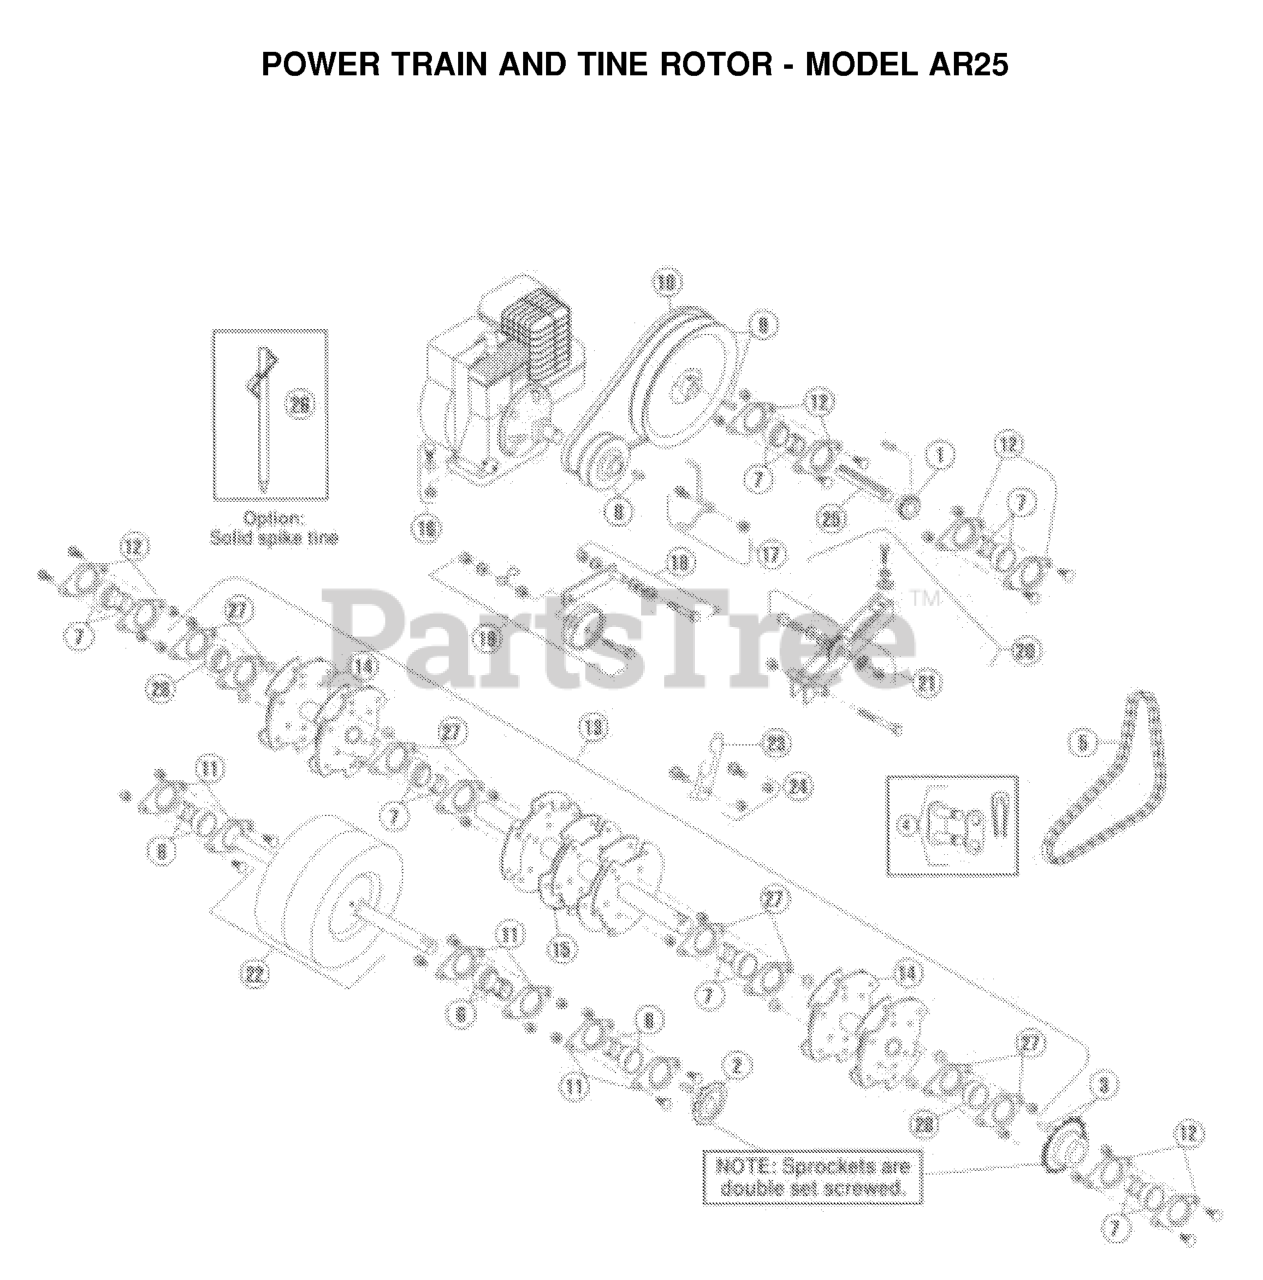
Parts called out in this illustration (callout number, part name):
1	SPROCKET
2	SPROCKET
3	SPROCKET
4	CHAIN LINK #50
5	CHAIN, #50 PERMA LUBE ROLLER
6	BEARING
7	BEARING 1"
8	V-PULLEY, A-4"X3/4" BORE W/KEY
9	V-PULLEY
10	ENGINE BELT - V
11	STAMPING KIT
12	STAMPING KIT
13	TINE ROTOR
14	OUTER ROTOR
15	CENTER TINE
16	FASTENER KIT
17	BELT KEEPER KIT
18	IDLER ARM KIT
19	IDLER PULLEY KIT
20	IDLER ARM KIT
21	IDLER SPROCKET KIT
22	FRONT WHEEL & SHAFT KIT
23	TINE SET
24	BOLT KIT
25	JACK SHAFT, W/ KEY
26	SPIKE SET NLA
27	STAMPING KIT
28	BEARING
540007103	BOLT KIT
540007112	TINE SET
